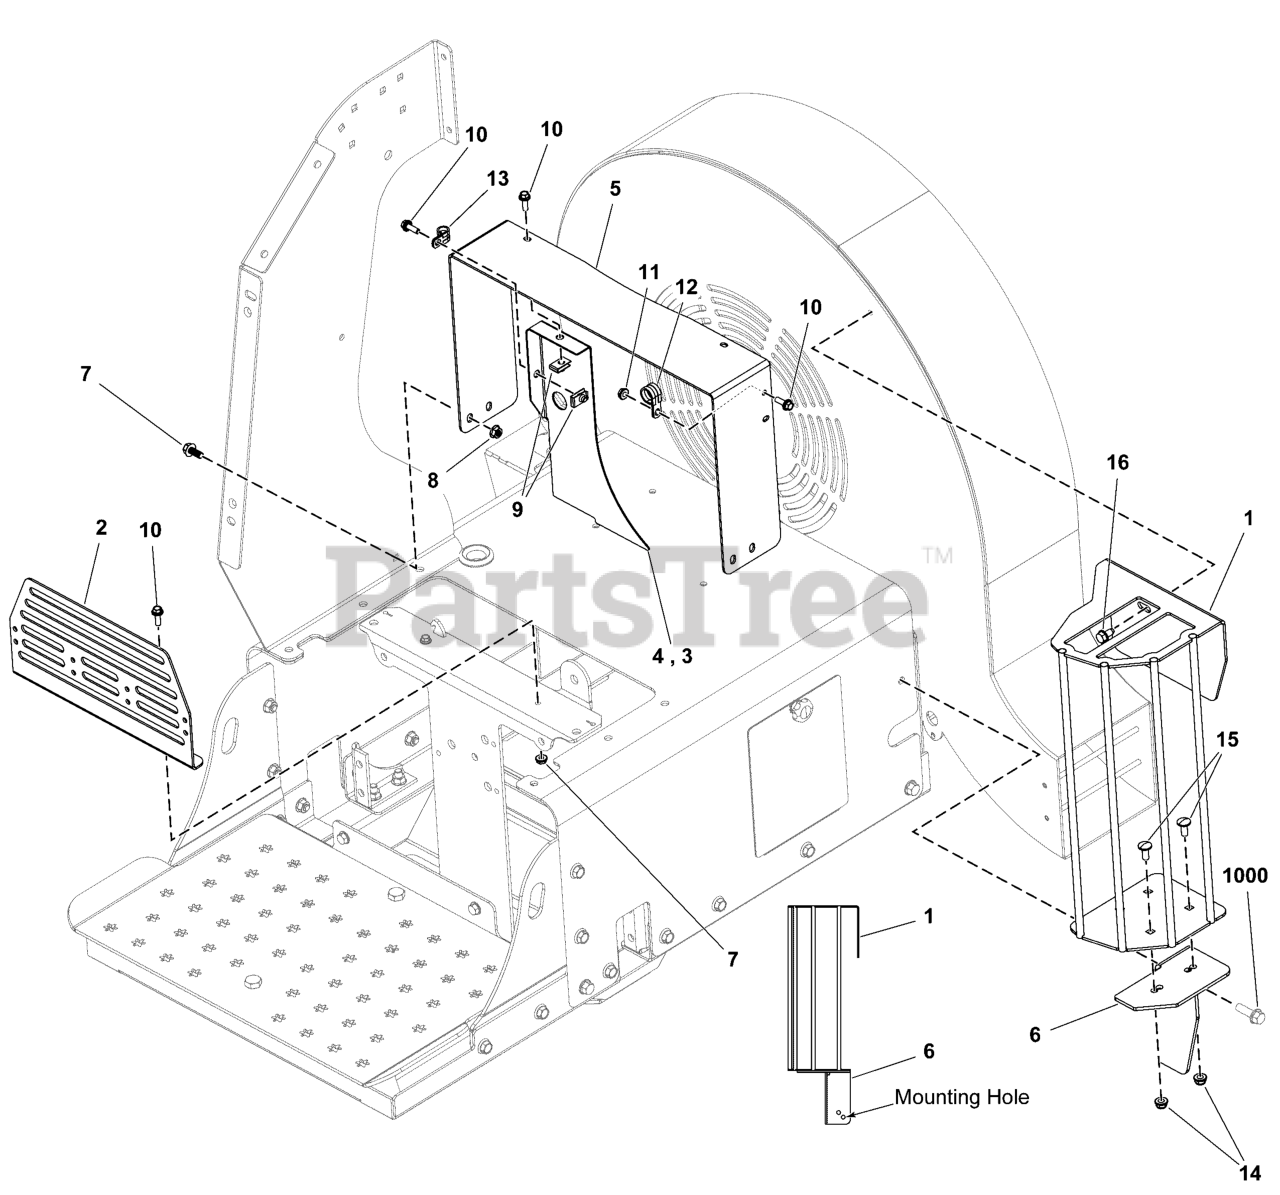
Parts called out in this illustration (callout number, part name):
1	WELD, MUFFLER GUARD, HURRICANE, X3000
2	MOUNT, OIL RESERVOIR, CE - BLK
4	PLATE, LH REAR BELT GUARD, CE - ORG
5	PLATE, REAR BELT GUARD, CE - ORG
6	WELD, LOWER SUPPORT, MUF GUARD - BLK
7	SCREW, 5/16-18x0.750, GR5, WHIZ-LOCK, ZC
8	NUT, 5/16-18 HEX SERRATED FLANGE (SMALL)
9	BODY CLIP, 1/4-20 X 1/2" DEEP
10	BOLT, 1/4-20 X 3/4, FLANGE, CZ
11	NUT, 1/4-20 HEX SERR. FLANGE
12	CLAMP, VINYL INSULATED, .75
13	CLAMP, VINYL INSULATED, .50
14	NUT, 5/16-18 HEX NYLOCK FLANGE NUT
15	RHSSNB,5/16-18 X 3/4 GR5 ZINC/CLEAR
16	SCREW,5/16-18X0.625,WSHR,THD-ROLL,ZC/CL
1000	Refer to: Main Frame Group
